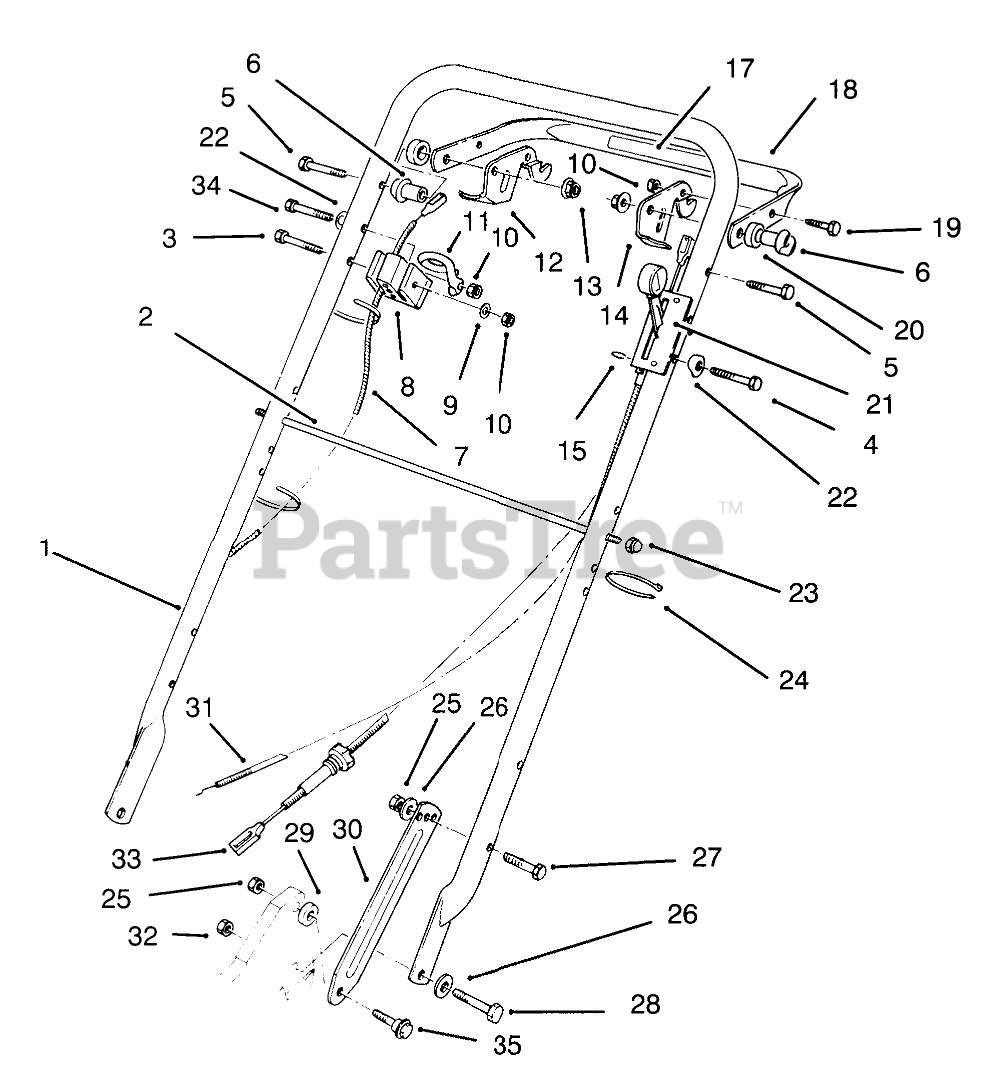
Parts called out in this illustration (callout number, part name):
1	Handle
2	ROD-SUPPORT, BAG
3	SCREW-HH
4	SCREW-HH
5	SCREW-HH
6	SPACER-SUPPORT
7	CABLE - BRAKE
8	SUPPORT-CABLE
9	WASHER-FLAT
10	NUT-LOCK, NI
11	GUIDE-ROPE
12	LEVER-CONTROL
13	NUT-LOCK, NI
14	LEVER-CONTROL
15	E-RING
17	DECAL/TRACTION CONTROL
18	Bar-Control
19	SCREW-HH
20	SPACER-NYLON
21	No. 2 Lift Arm
22	WASHER
23	NUT-CAP
24	TIE-CABLE
25	NUT-LOCK, NI
26	WASHER-BELLEVILLE
27	SCREW-HH
28	SCREW-HH
29	SPACER
30	Latch-Handle
31	CABLE-THROTTLE
32	NUT-LOCK, NI
33	CABLE-TRACTION
34	SCREW-HH
35	SCREW-SHOULDER
